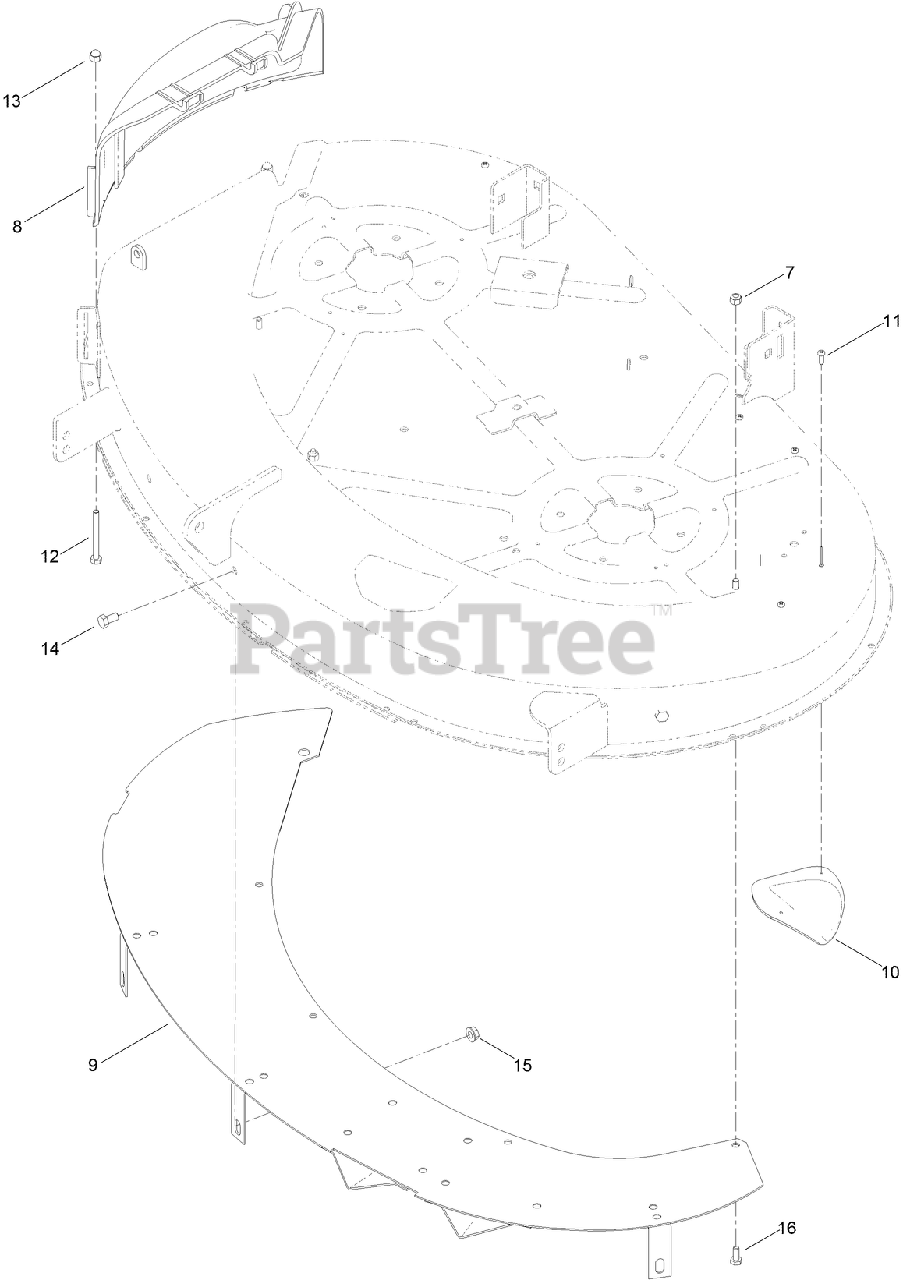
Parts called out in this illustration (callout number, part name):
7	NUT-LOCK, NI
8	COVER-DISCHARGE
9	BAFFLE UPPER ASM
10	PLATE-KICKER
11	SCREW-PPH
12	SCREW-HH
13	NUT-CAP
14	SCREW-HH
15	NUT-HF
16	SCREW-HH
